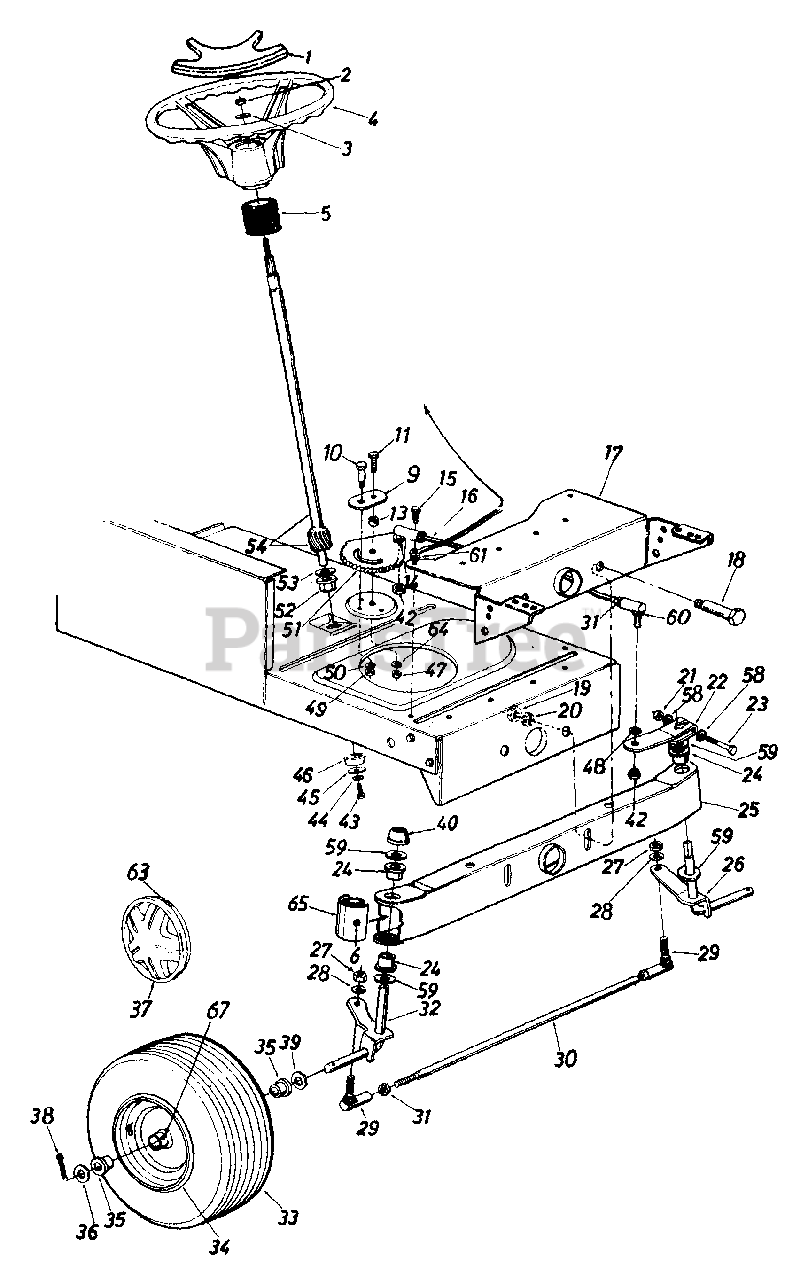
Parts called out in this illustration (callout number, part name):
1	Steering Wheel Cap
2	Hex L-Nut 5/16-24 Thd.
3	Belleville Wash. .345" I.D.
4	Steering Wheel
5	Steering Bellow - 9"
6	Grease Fitting
9	Retainer Plate
10	Shoulder Bolt .437" Dia. x .35" Lg. - 5/16-18 Thd.
11	Hex Bolt 3/8-24 x 1.0" Lg. (Grade 5)
13	Spacer .380" I D. x .625" O.D. x .227
14	L-Wash. 3/8" I.D. (H.D.)
15	Hex Wash. Hd. Self-Tap Scr.
16	Steering Drag Link
18	Shoulder Bolt .498" Dia. x 2.04" Lg. - 3/8-16 Thd.
19	Hex Nut 3/8-16 Thd.
20	L-Wash. 3/8" I.D.
21	Hex L-Nut 5/16-24 Thd.
22	Steering Arm Front Axle
23	Hex Bolt 5/16-24 x 2.00" Lg. (Grade 5)
24	Hex Flg. Brg. .632 I.D.
26	Front Axle Ass'y. - L.H.
27	Hex Nut 3/8-24 Thd."
28	L-Wash. 3/8" I.D.
29	Ball Joint 3/8-24 Thd.
31	Hex Jam Nut 3/8-24 Thd.
32	Front Axle Ass'y. - R.H.
36	Fl-Wash. .635" I.D. x 1.59" O.D.
37	Front Wheel Hub Cap
38	Cotter Pin 1/8" Dia. x 1.25"
39	Fl-Wash. .640" I.D. x 1.24" O.D.
40	Push Cap 5/8" Dia. Rod
42	Hex Jam Nut 3/8-24 Thd.
43	Hex L-Bolt 5/16-18 x .62"
44	L-Wash. 5/16" I.D.
45	Fl-Wash. .33" I.D. x 1.25" O.D.
46	Spacer (Plastic)
47	Hex Cent. L-Nut 3/8-24 Thd.
48	L-Wash. 3/8" I.D.
49	Hex Cent. L-Nut 5/16-18 Thd.
50	L-Wash. 5/16" I.D.
51	Steering Gear Segment
52	Hex . Flg. Brg. .634 I.D.
53	Fl-Wash. (Hardened)
54	Steering Shaft
58	Wave-Wash. .32" I.D. x .62" O.D
59	Fl-Wash. (Hardened)
60	Drag Link Ball Joint 3/8-24 Thd.
61	Ext. L-Wash. 5/16" I.D.
63	Spring Clip
64	Bell-Wash. .39" I.D. x 1.38" O.D.
65	Pivot Bar End Cap
67	Grease Fitting
